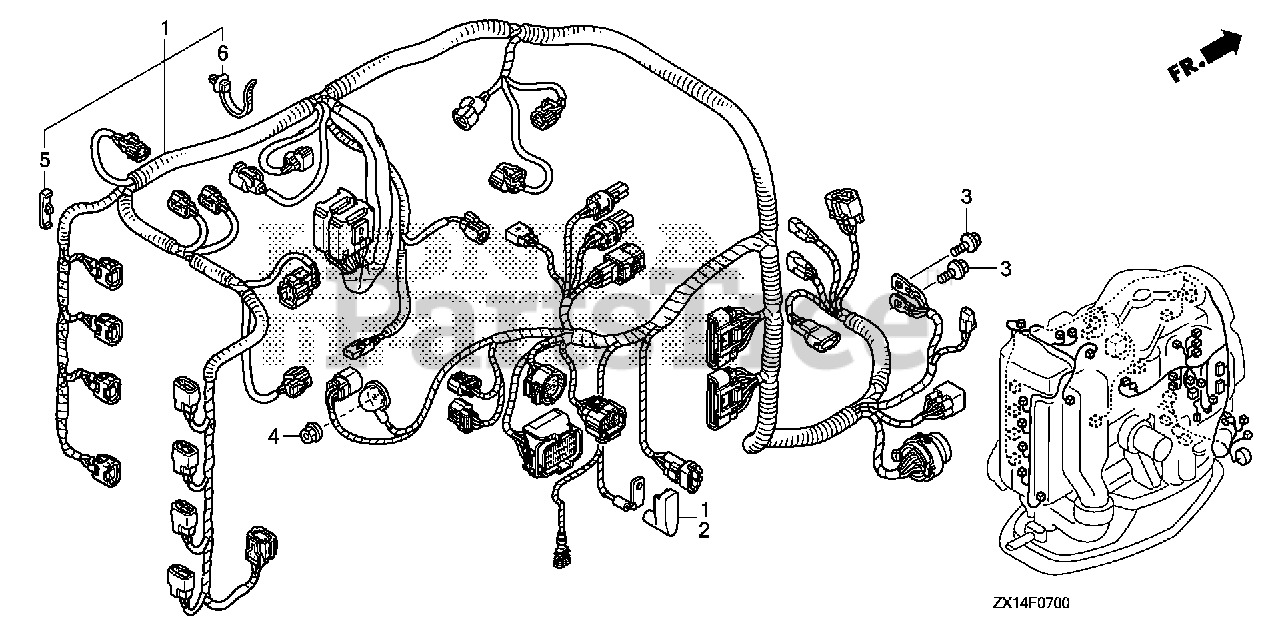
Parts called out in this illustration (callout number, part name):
1	WIRE HARNESS ASSY., MAIN
2	COVER B, TERMINAL (L)
3	BOLT, FLANGE (6X12)
4	NUT-WASHER (6MM)
5	CLIP, WIRE HARNESS
6	CLIP, HARNESS BAND (145MM) (BLACK)
